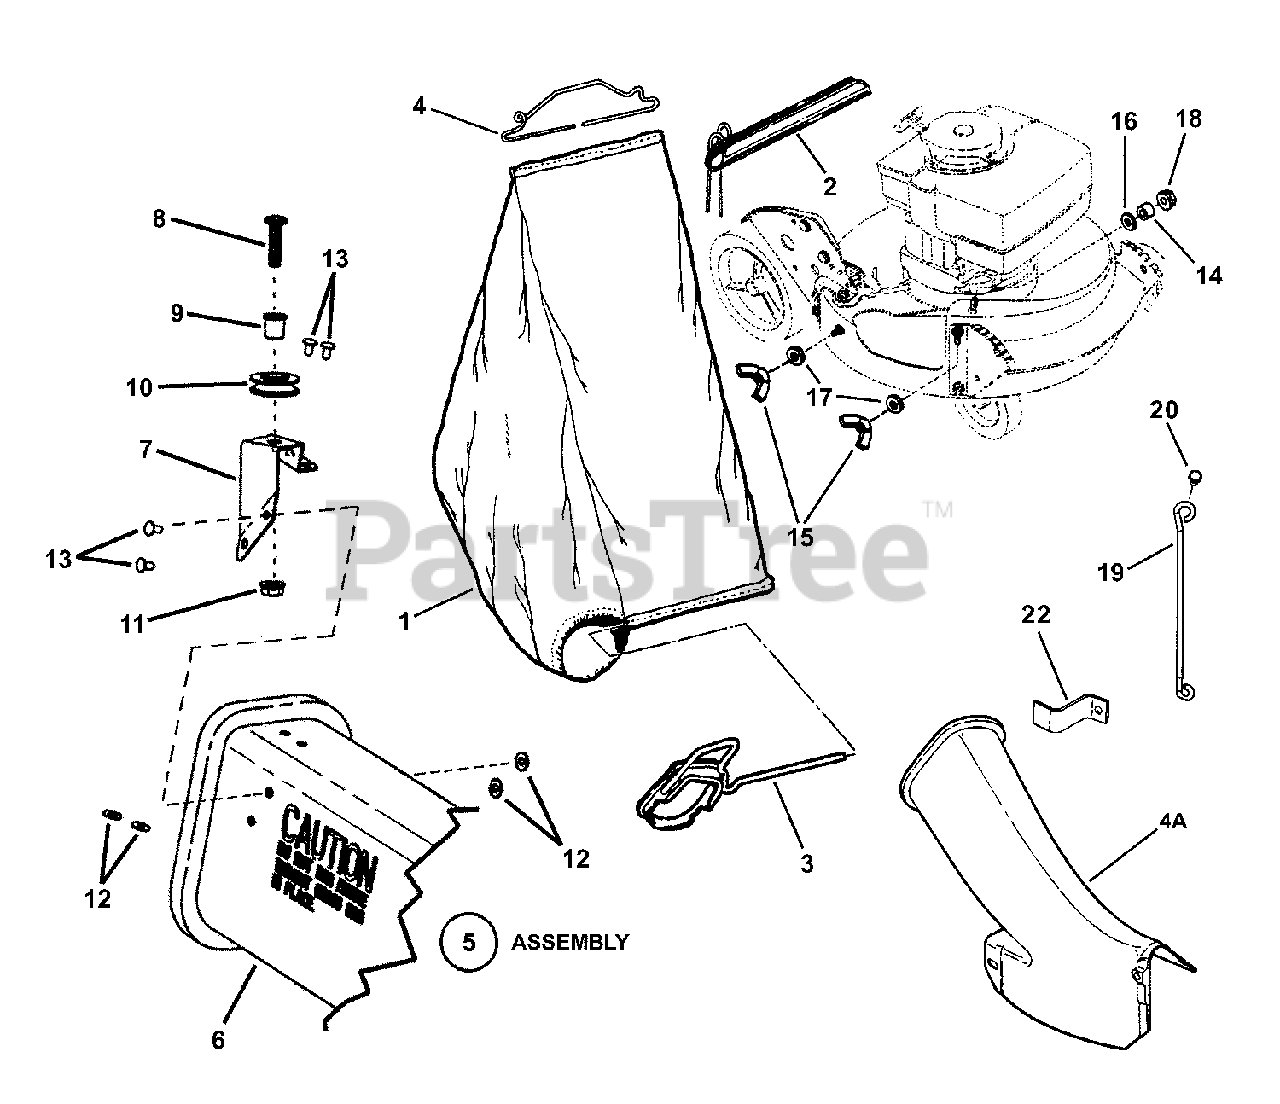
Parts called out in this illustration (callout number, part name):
1	* GRASS BAG, Slider Type (Black w/Gray Letters)
2	ASSEMBLY, Slider
3	CONNECTOR, Grass Bag
4	WIRE, Bag Connector (12" Wide)
4A	ADAPTER, Grass Bag
5	ASSEMBLY, Grass Bag Adapter (Incl. items 11 thru 18)
6	ADAPTER, Grass Bag
7	BRACKET, Rope Pulley
8	SCREW, 5/16-18 x 1-1/4" Pan Head Machine
9	BUSHING, Flange
10	PULLEY, Plastic
11	NUT, 5/16-18 Hex Flange Lock GR5
12	WASHER, 15/32" Flat
13	RIVET, 3/16 x .344
14	SPACER, .316 I.D. x .375 O.D. x .310 thick
15	NUT, 5/16-18 Wing (Nylon Patch)
16	RETAINER, 5/16" Bolt
17	WASHER, 5/16" Flat
18	NUT, 5/16-18 Hex Large Flange Center Lock
19	BRACE, Bag Adapter, KWV
20	SCREW, M6 x 1.0 x 30MM Hex Head Cap
22	STANDOFF
